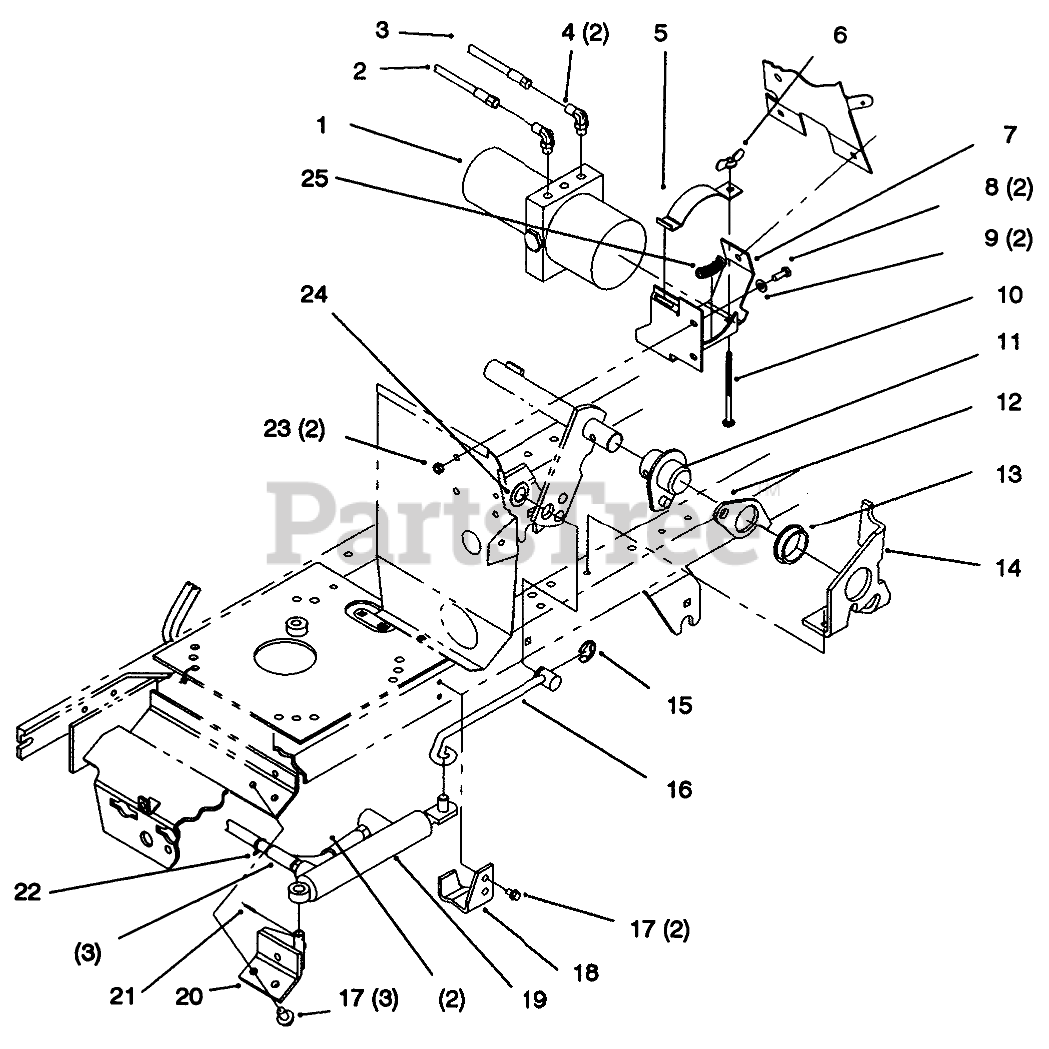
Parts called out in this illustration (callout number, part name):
1	PUMP - HYDRAULIC
2	HOSE - HYDRAULIC
3	HOSE - HYDRAULIC
4	RING-O MALE JIC 90 DEG
5	CLAMP-HYDRAULIC (BLACK)
6	NUT-WING
7	BRKT- PUMP MOUNTING (BLACK)
8	SCREW-HH
9	WASHER-FLAT
10	SCREW-CARR
11	Cap-End
12	ARM - HOC
13	BUSHING
14	BRACKET-ARM, LIFT
15	E-RING
16	WA - LIFT ROD
17	SCREW-HWHTF
18	BRACKET - SUPPORT (BLACK)
19	CYLINDER - HYDRAULIC
20	Bracket-Cyl Mtg
21	PIN-COTTER
22	TIE-CABLE
23	NUT-HEX
24	WASHER
25	TUBING - CONDUIT
